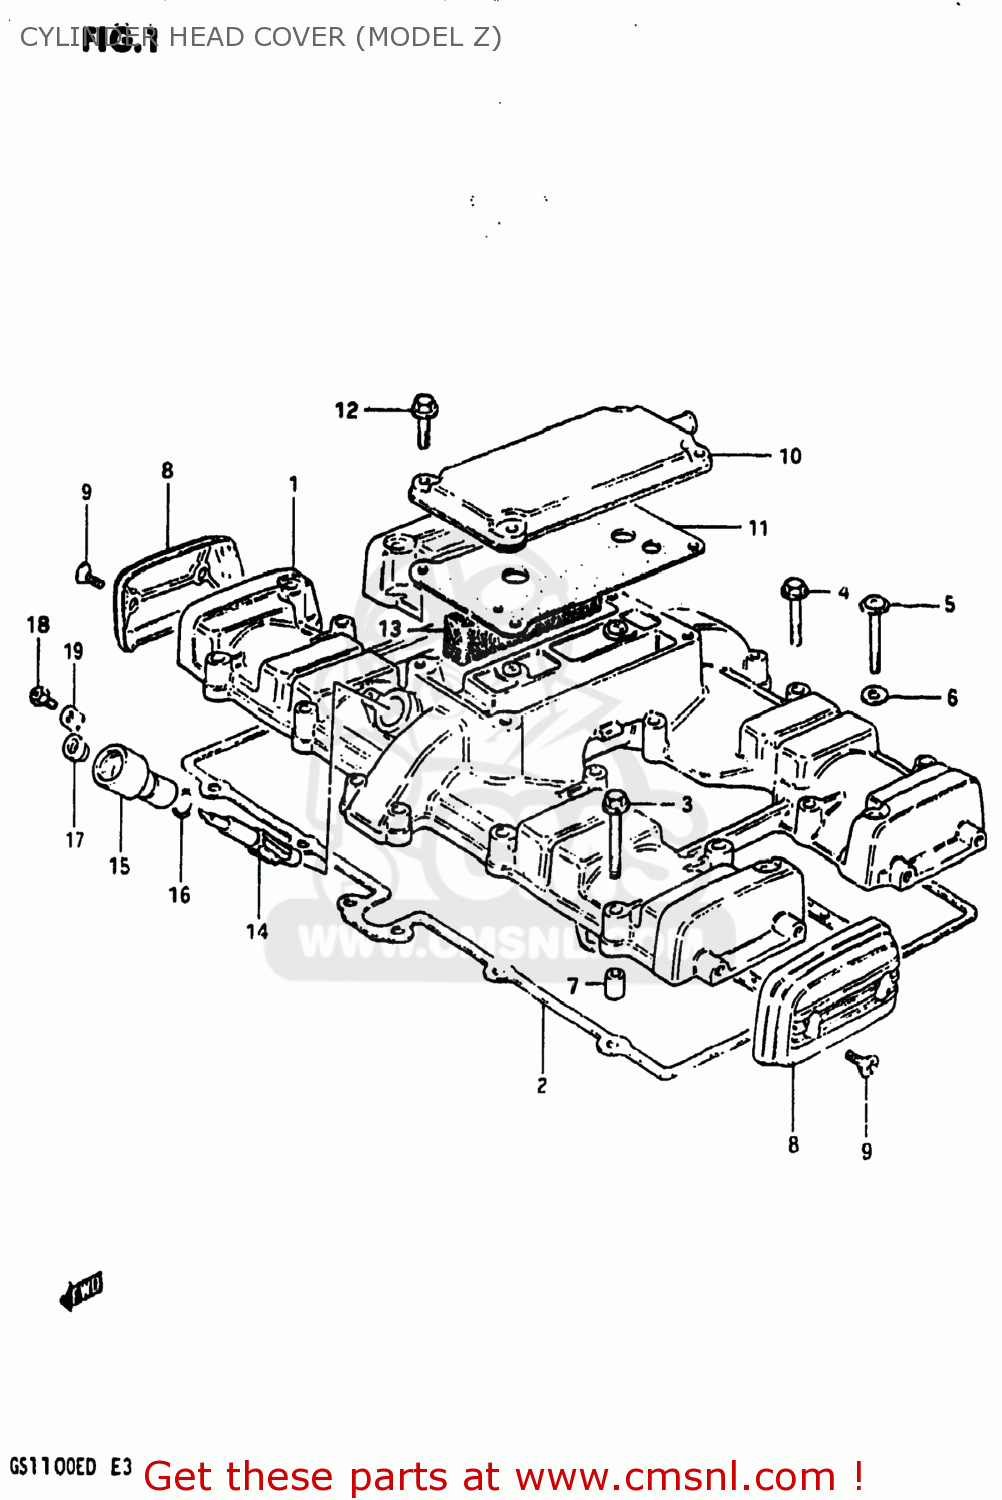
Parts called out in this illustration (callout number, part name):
1	COVER,CYLINDER HEAD
2	GASKET,CYLINDER HEAD COVER (MCA)
3	BOLT
4	BOLT 6X35
5	SCREW 6X40
6	GASKET (NAS)
7	PIN(6.2X8X11)
8	CAP,CYLINDER HEAD COVER
9	SCREW(5X12)
10	COVER,BREATHER
11	GASKET (MCA)
12	BOLT,REAR
13	COVER,BREATHER
14	GEAR,TACHOMETER DRIVEN
15	SLEEVE,TACHOMETER DRIVE
16	SEAL,TACHOMETER DRIVEN
17	SEAL,OIL(5X12X8)
18	SCREW(5X12)
19	PLATE,TACH DRIVE GEAR SLEEVE
